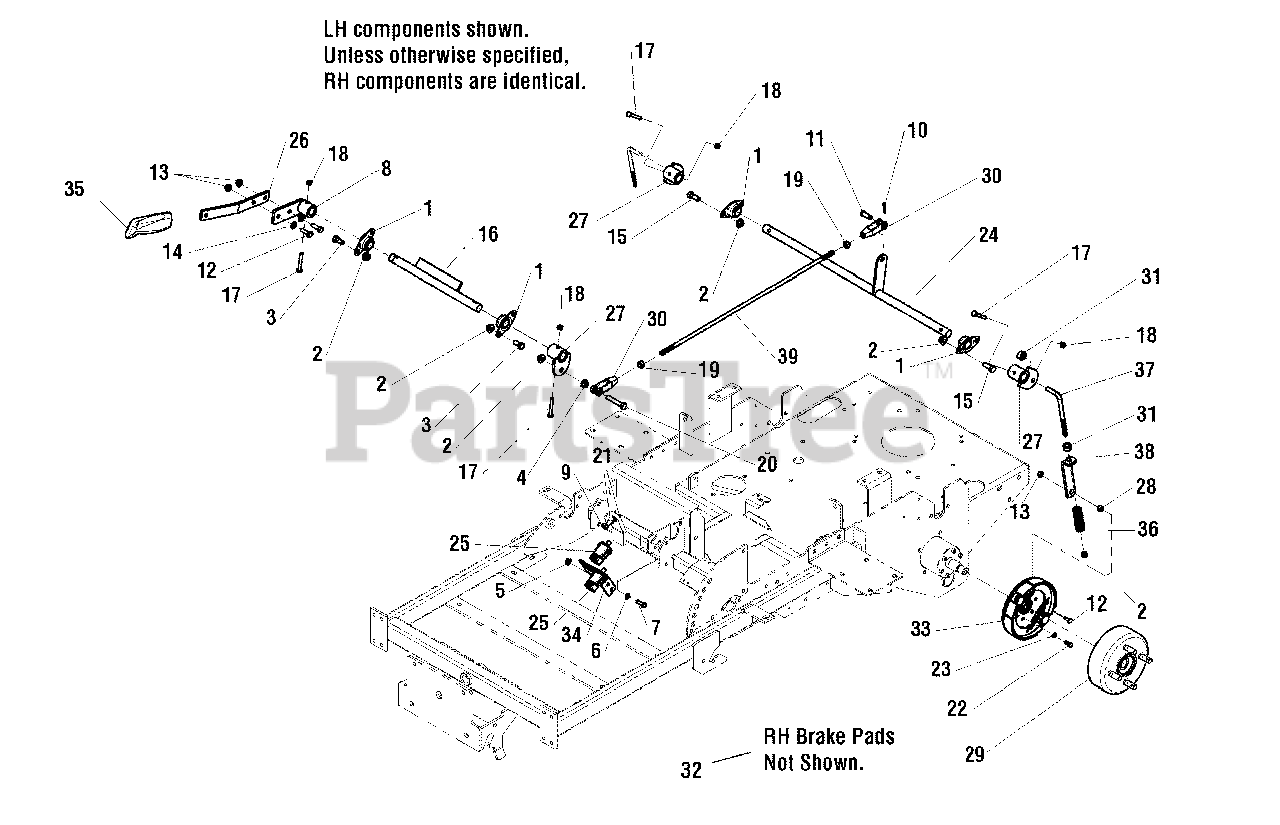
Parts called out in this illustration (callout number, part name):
1	BEARING, BRONZE FLANGE, 3/4"
2	NUT, 3/8-16 HEX NYLOCK FLANGE
3	BOLT, 3/8-16 X 3/4" GD5 CZ
4	NUT, 3/8-16 HEX
5	NUT, 1/4-20 HEX SERR. FLANGE
6	WASHER, 1/4 SAE
7	BOLT, 1/4-20 X 5/8" GD5
8	WELD, MOUNT BRAKE LEVER
9	BOLT, 3/8-16 X 2" GD 5 TFL CZ
10	PIN, COTTER, 1/8" X 3/4"
11	PIN, CLEVIS, 3/8" X 1"
12	BOLT, 5/16-18 X 1" GD5
13	NUT, 5/16-18 HEX NYLOCK FLANGE
14	WASHER, 5/16" SAE
15	BOLT, 3/8-16 X 3/4", ALLEN BUTTON
16	WELD, SHAFT BRAKE LEVER
17	BOLT, 1/4-20 X 1-1/2" GD5
18	NUT, 1/4-20 HEX SIDE LOCK
19	NUT, HEX 3/8-24
20	BOLT, 3/8-16 X 2, GD5, CZ
21	NUT, 3/8-16 HEX LG. SERR FLG
22	BOLT, M6-1.0 X 14MM
23	WASHER, 1/4" LOCK
24	WELD, SHAFT, REAR BRAKE
25	SWITCH PLUNGER NO/NC SNAP IN
26	HANDLE, BRAKE LEVER
27	WELD, PIVOT LINKAGE MOUNT
28	SPACER, .38 X .50 X .27
29	DRUM, BRAKE, 4-BOLT
30	CLEVIS, 3/8-24 PLASTIC
31	COLLAR, 3/8" SET
33	BRAKE ASSEMBLY, LH
34	BRACKET, SWITCH MOUNT
35	GRIP, BLACK FLEXIBLE
36	SPRING, BRAKE
37	ROD, BRAKE ADJUSTMENT
38	LINK, BRAKE LOCK
39	ROD, BRAKE ENGAGEMENT 36"
